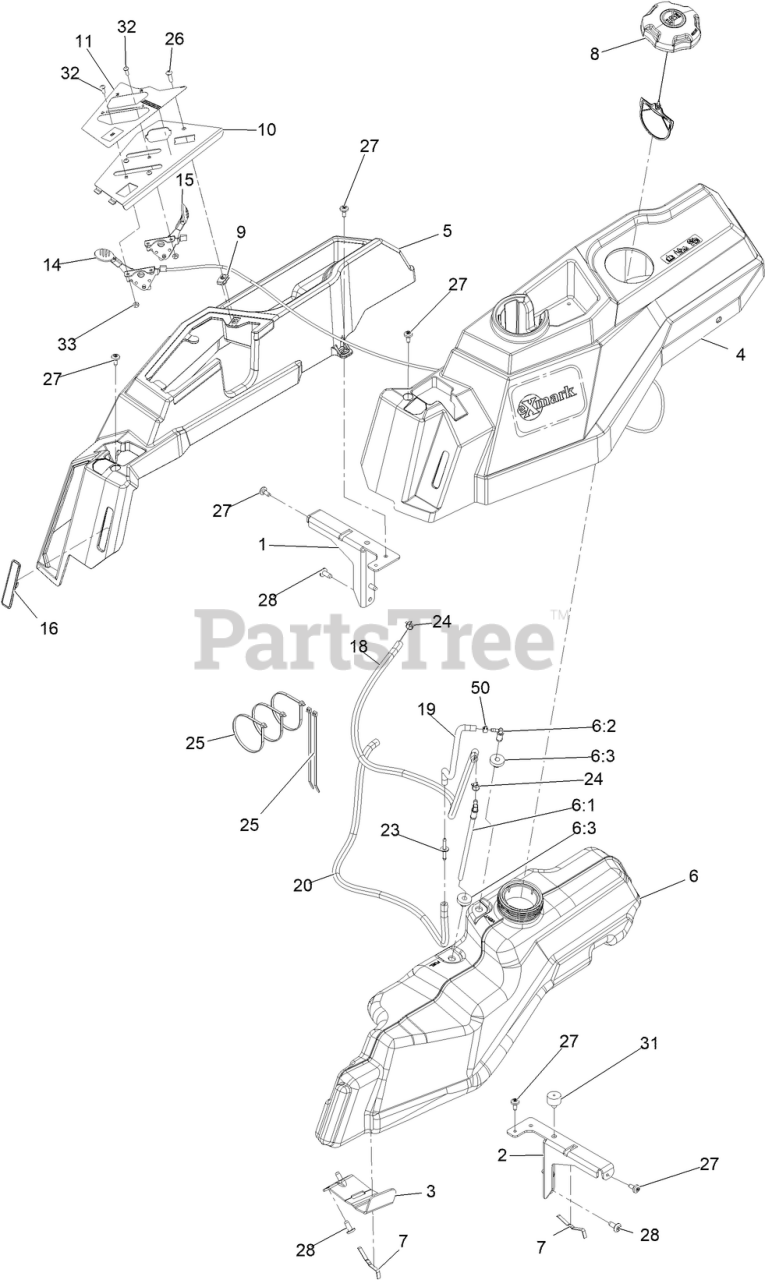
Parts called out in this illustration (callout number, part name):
1	SUPPORT-POD, RH
2	SUPPORT-POD, LH
3	SUPPORT-TANK, FUEL
4	POD- LH
5	POD- RH
6	TANK-FUEL ASM
6:1	Connector-Elbow, 90 DEG
6:2	Fitting-Elbow 90
6:3	BUSHING
7	SPRING
8	CAP-FUEL, RATCHETING
10	PANEL- CONTROL
11	DECAL-CONTROL PANEL
14	ASM,THROTTLE CABLE
15	CABLE-CONTROL, CHOKE
16	PLUG-SC
18	HOSE-FUEL
19	Hose-Fuel
20	Hose, Fuel
23	Adapter Orifice
24	CLAMP-HOSE
25	TIE-CABLE
26	SCREW-PRH
27	SCREW-SHOULDER
31	BUMPER-GROMMET
32	SCREW-PPH
33	NUT-LOCK, NI
50	CLAMP-HOSE
